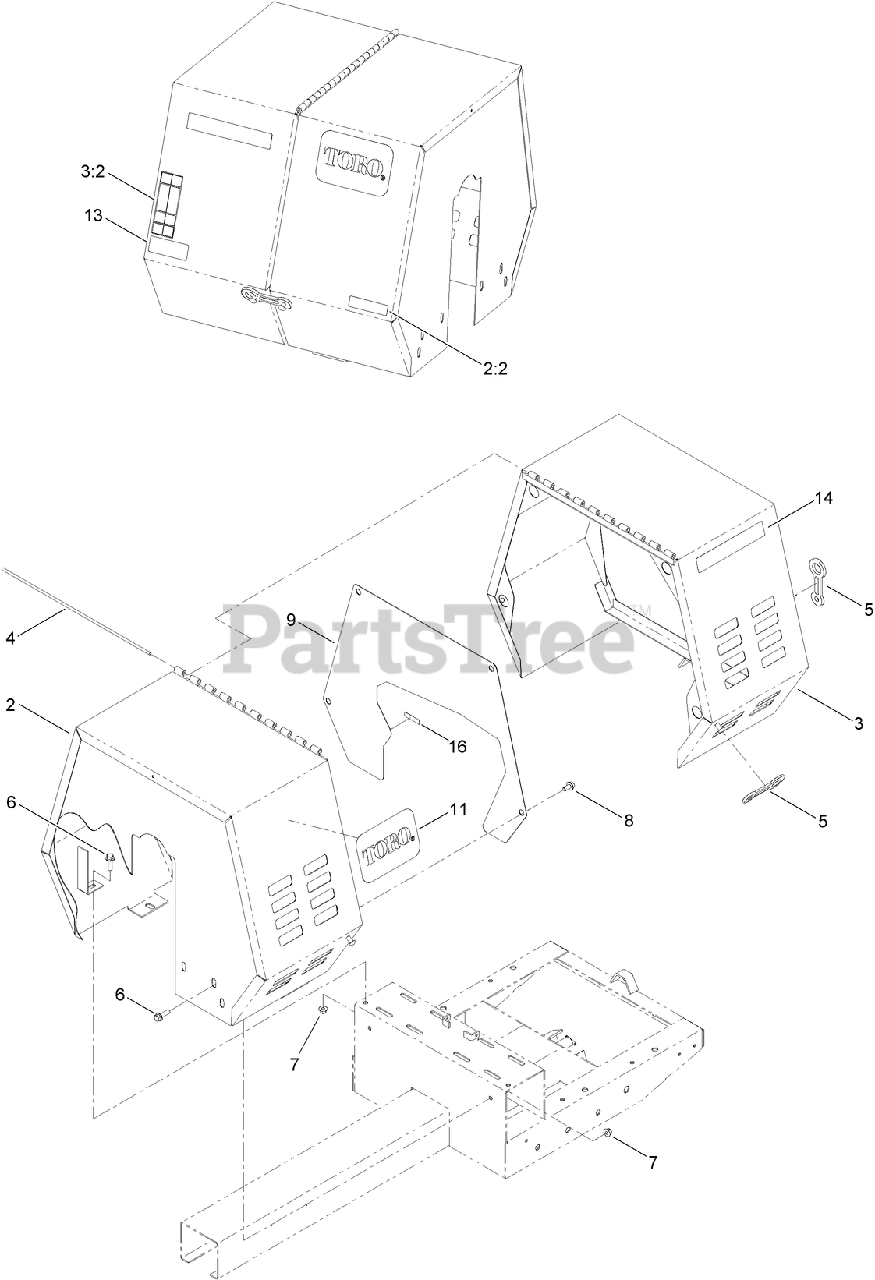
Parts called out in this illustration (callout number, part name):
2	STATIONARY COWL ASM
2:2	DECAL-ARRESTER, SPARK
3	MOVABLE COWL ASM
3:2	DECAL-WARNING
5	LATCH-RUBBER
6	SCREW-HHF
7	NUT-HF, NI
8	SCREW-HWH
9	PLATE-ACCESS, BELT
11	DECAL
14	DECAL-MM-658H
16	DECAL-GREASE
